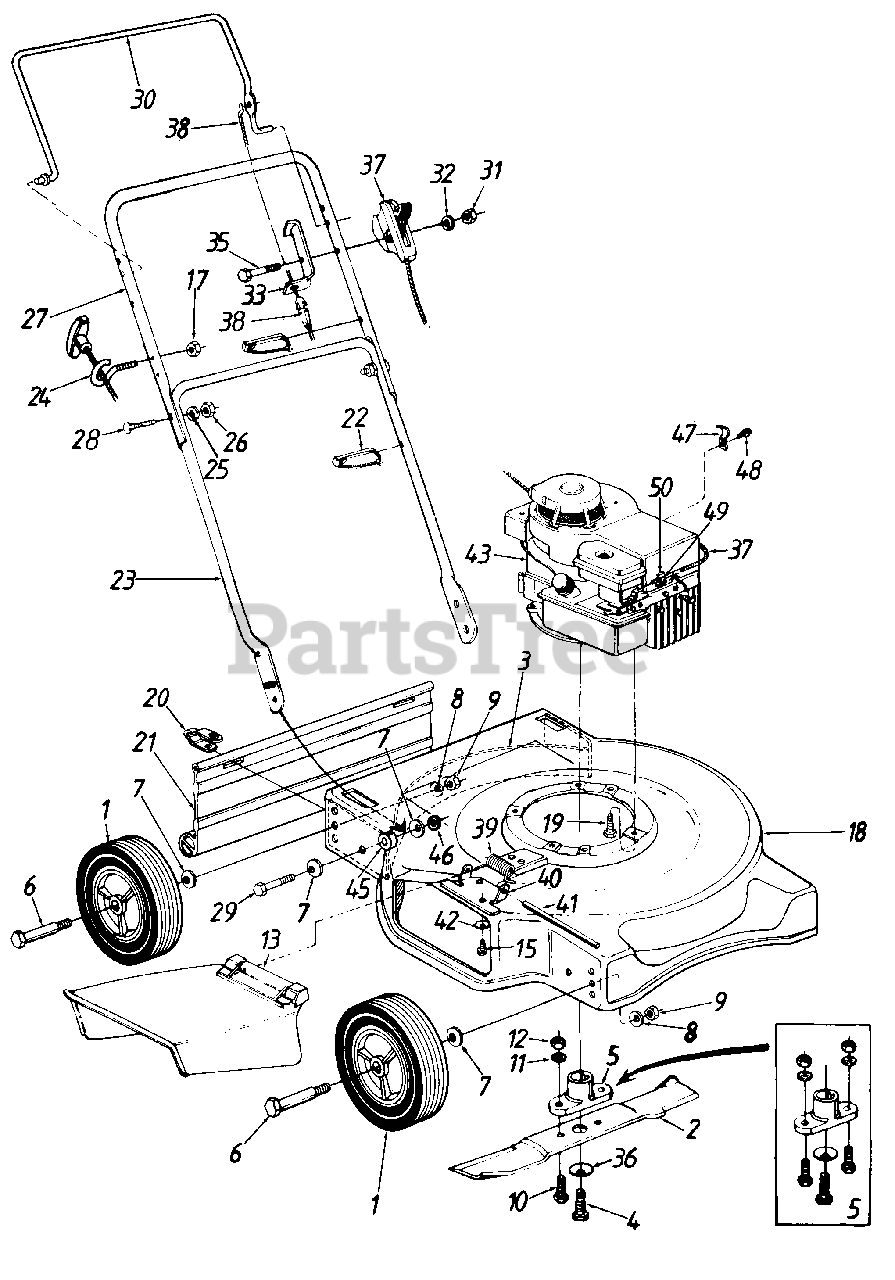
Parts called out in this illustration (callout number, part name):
1	Wheel Ass'y. Complete
2	20" Blade
5	Blade Adapter Kit (Keyed)
6	Axle Bolt
7	Bell-Wash. .380" I.D. x .88"
8	Bell-Wash. .39" I.D. x 1.13"
9	Hex Nut 3/8-16 Thd.
10	Hex Bolt 3/8-24 x 1" Lg.
11	L-Wash. 3/8" I.D.
12	Hex Nut 3/8-24 Thd.
13	Chute Deflector Ass'y.
15	Self-Tap Scr. 1/4-20 x .5" Lg.
17	Hex L-Nut 1/4-20 Thd.
18	20" Deck Ass'y.
19	Hex Wash. Hd. Scr. 3/8-16 x 1" Lg.
20	Hinge Clip
21	Rear Flap 16.75" Lg.
22	Cable Tie
23	Lower Handle
24	Rope Guide
25	L-Wash. 5/16" I.D.
26	Hex Nut 5/16-18 Thd.
27	Upper Handle
28	Curved Carriage Bolt 5/16-18 x 1.38" Lg.
29	Hex Bolt 3/8-24 x 1.5" Lg.
30	Control Handle
31	Hex Nut 1/4-20 Thd.
32	Spr. Wash. .265" I.D. x .562"
33	Cable Mounting Bracket
35	Hex Bolt 1/4-20 x 1.875" Lg.
36	Bell-Wash. .39" I.D.
37	Throttle Control Ass'y. Comp.
38	Control Cable-36"
39	Torsion Spring
40	Adapter Plate
41	Hinge Pin
42	Bell-Wash. 1/4" I.D.
43	Engine
45	Spacer
46	Hex L-Nut 3/8-24 Thd.
47	Casing Clamp
48	Hex B-Tap Scr. #10 x .88" Lg.
49	Casing Clamp
50	Hex Wash. Hd. AB-Tap Scr. #8 x .50" Lg.
